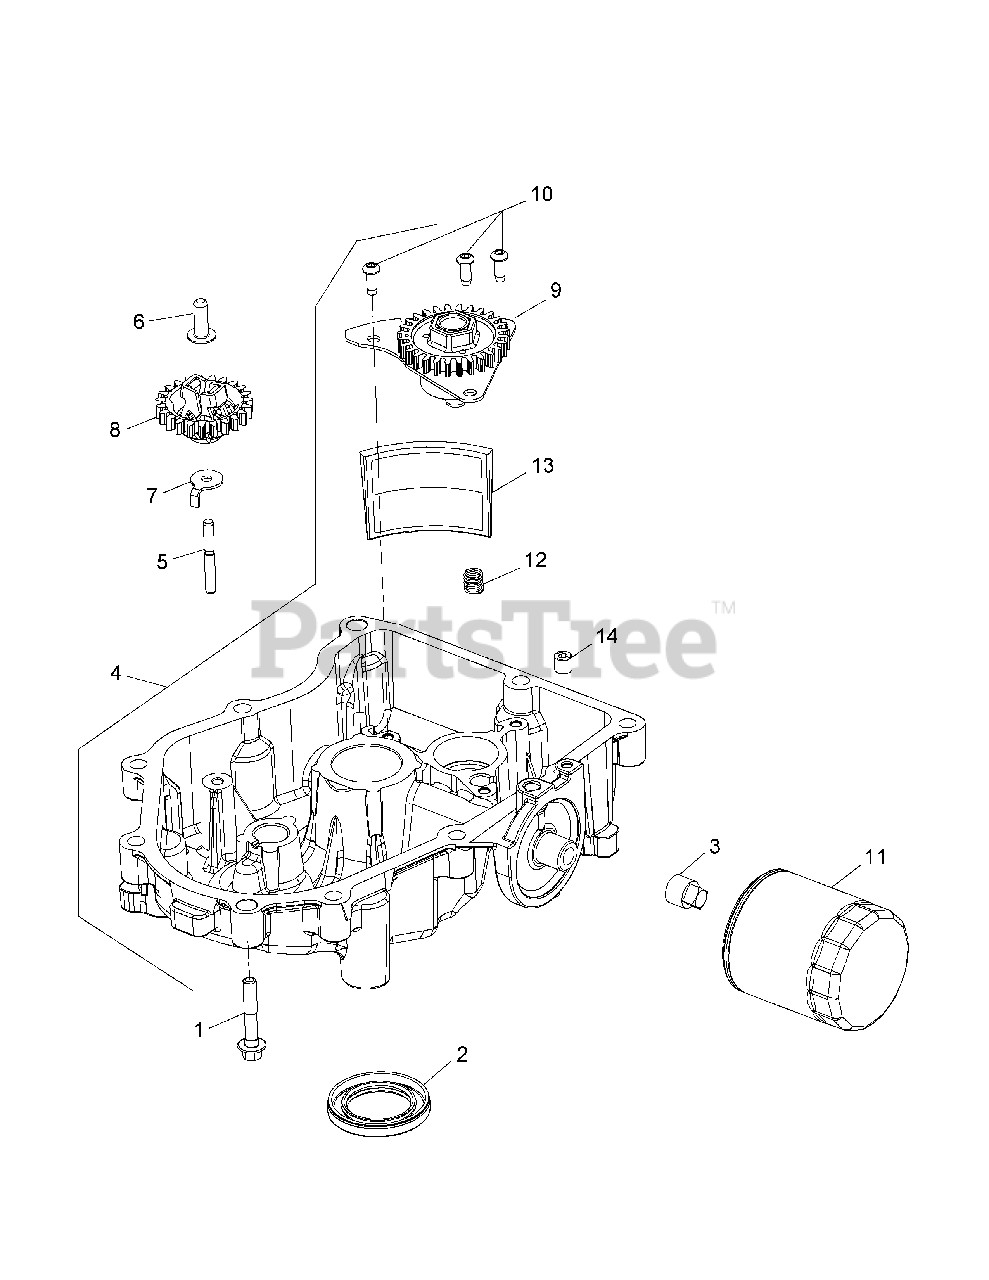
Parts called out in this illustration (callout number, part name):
1	Flange Screw, M8 x 1.25 x 45
2	Oil Seal, 2.38 x 1.45
3	Square Head Pipe Plug, 3/8
4	Oil Pan Assembly
5	Governor Gear Shaft
6	Governor Regulating Pin
8	Governor Gear Kit
9	Oil Pump Assembly
10	Button Head Screw
12	Compression Spring
14	Pipe Plug, 1/8
